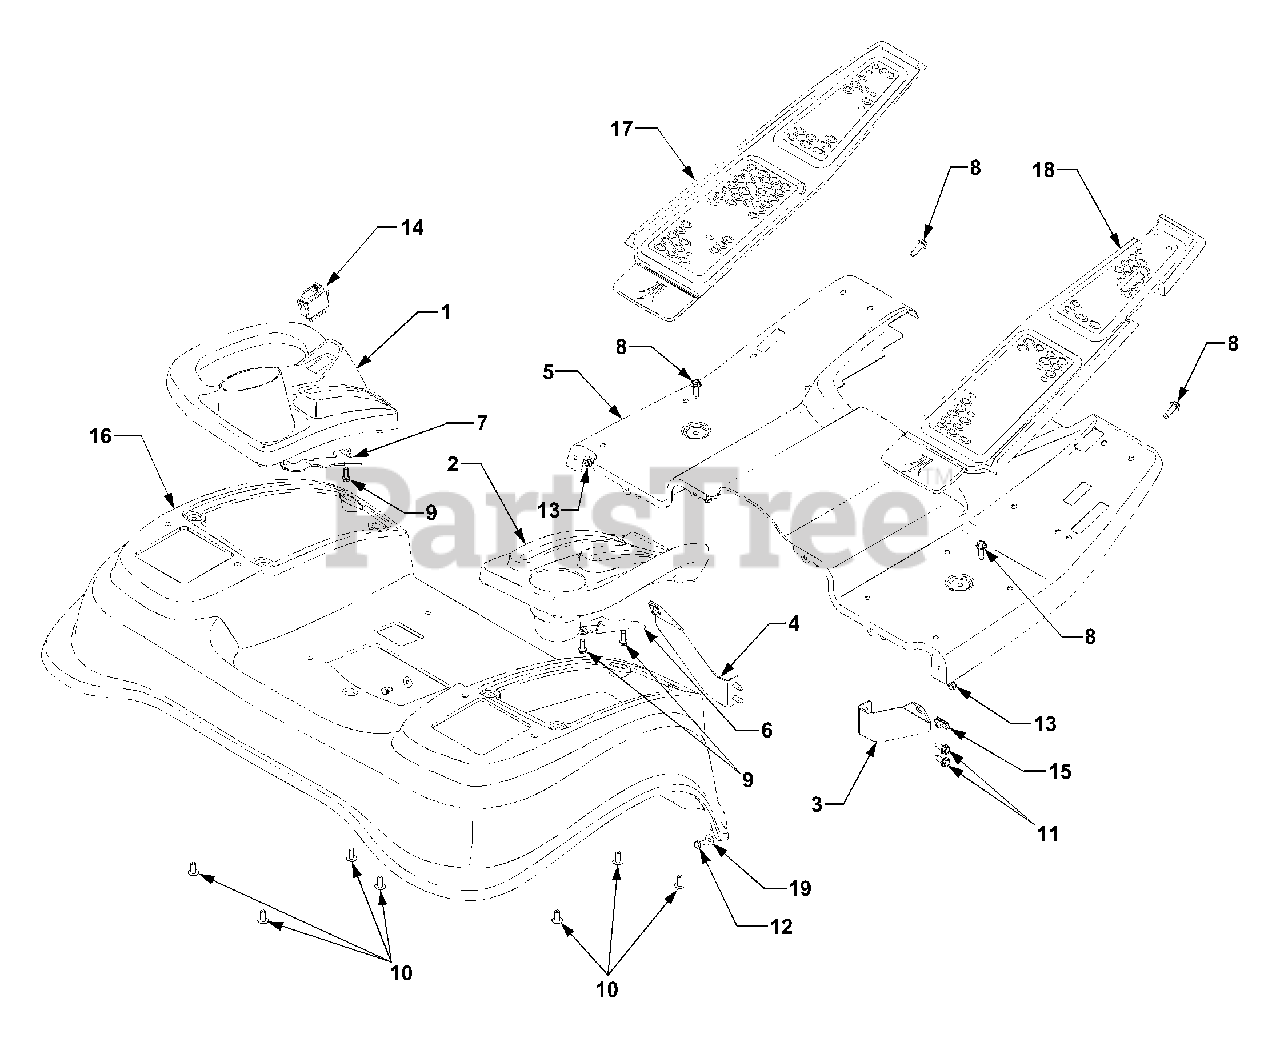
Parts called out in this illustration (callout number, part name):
1	Cover, Fender, LH
2	Cover, Fender, RH
3	Bracket, Running Board Mtg. RH
4	Bracket, Running Board Mtg. LH
5	Running Board
9	Screw, Hex Wash. Hd, Tapp 1/4-15 x .75
10	Screw, Truss Phillips Hd. 5/16-14 x .75
11	Screw, Hex Wash. Hd. Tapp 5/16-18 x .75
12	Screw, Hex Cap, 1/4-20 x .5 GR5
13	Nut, Hex Insert Lock, 1/4-20 GR8
14	Switch, PTO Reverse
15	Nut, Speed, 5/16-18
16	Fender
17	Pad, Floor - LH
18	Pad, Floor - RH
19	Washer, Flat, .26 x .72 x .06
